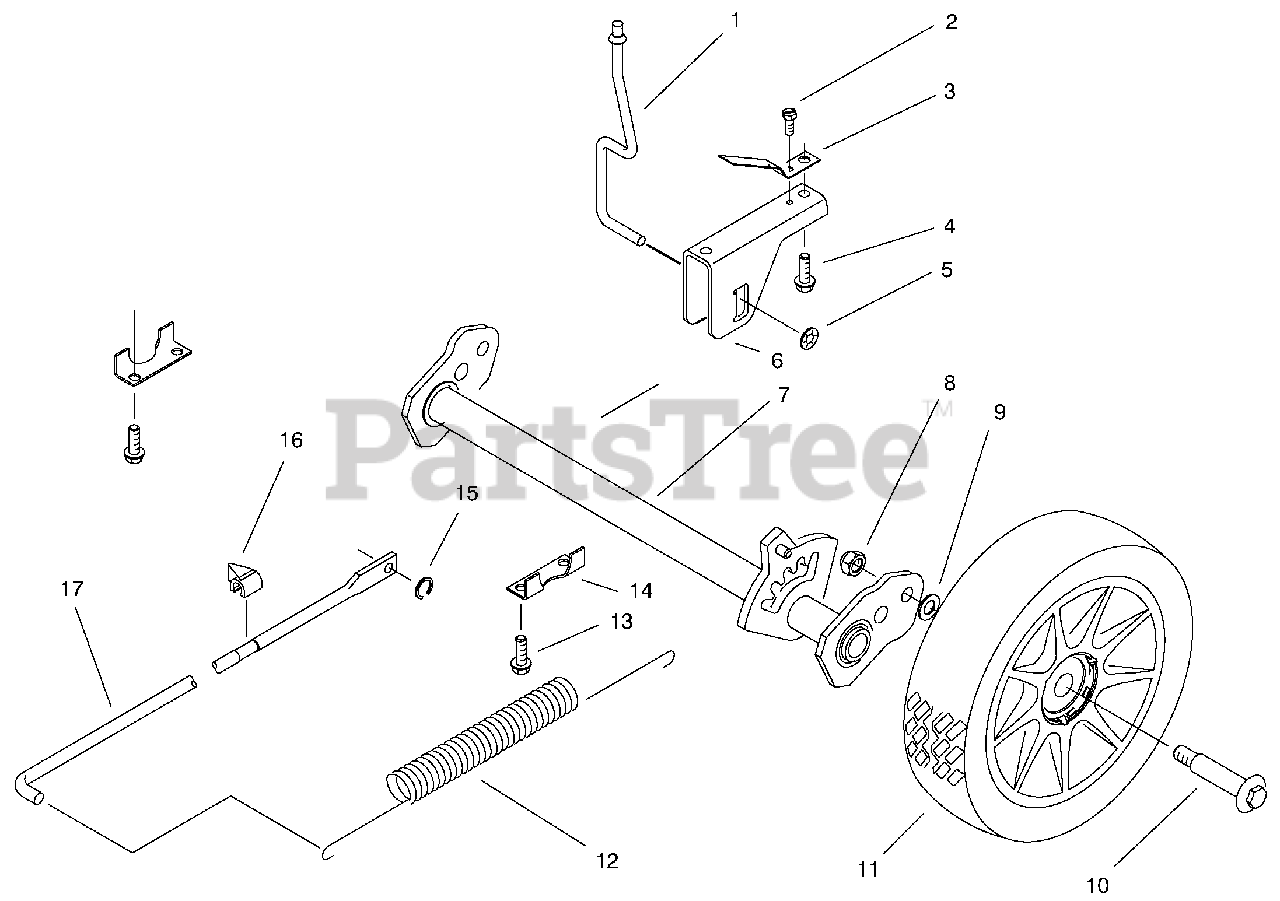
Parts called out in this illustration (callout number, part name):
1	TRIGGER ROD
2	SCREW 8 - 32 X 250
3	SPRING - TRIGGER RET
6	SADDLE - HOC
7	PIVOT - REAR WA
8	NUT-LOCK, NI
10	BOLT-SHOULDER
11	8" WHEEL ASSEMBLY
12	SPRING-COUNTERBALANCE
13	SCREW-HWH
14	REAR SECURING PLATE
15	GRIP RING
16	INDICATOR-HEIGHT OF CUT
17	ROD - LINK
